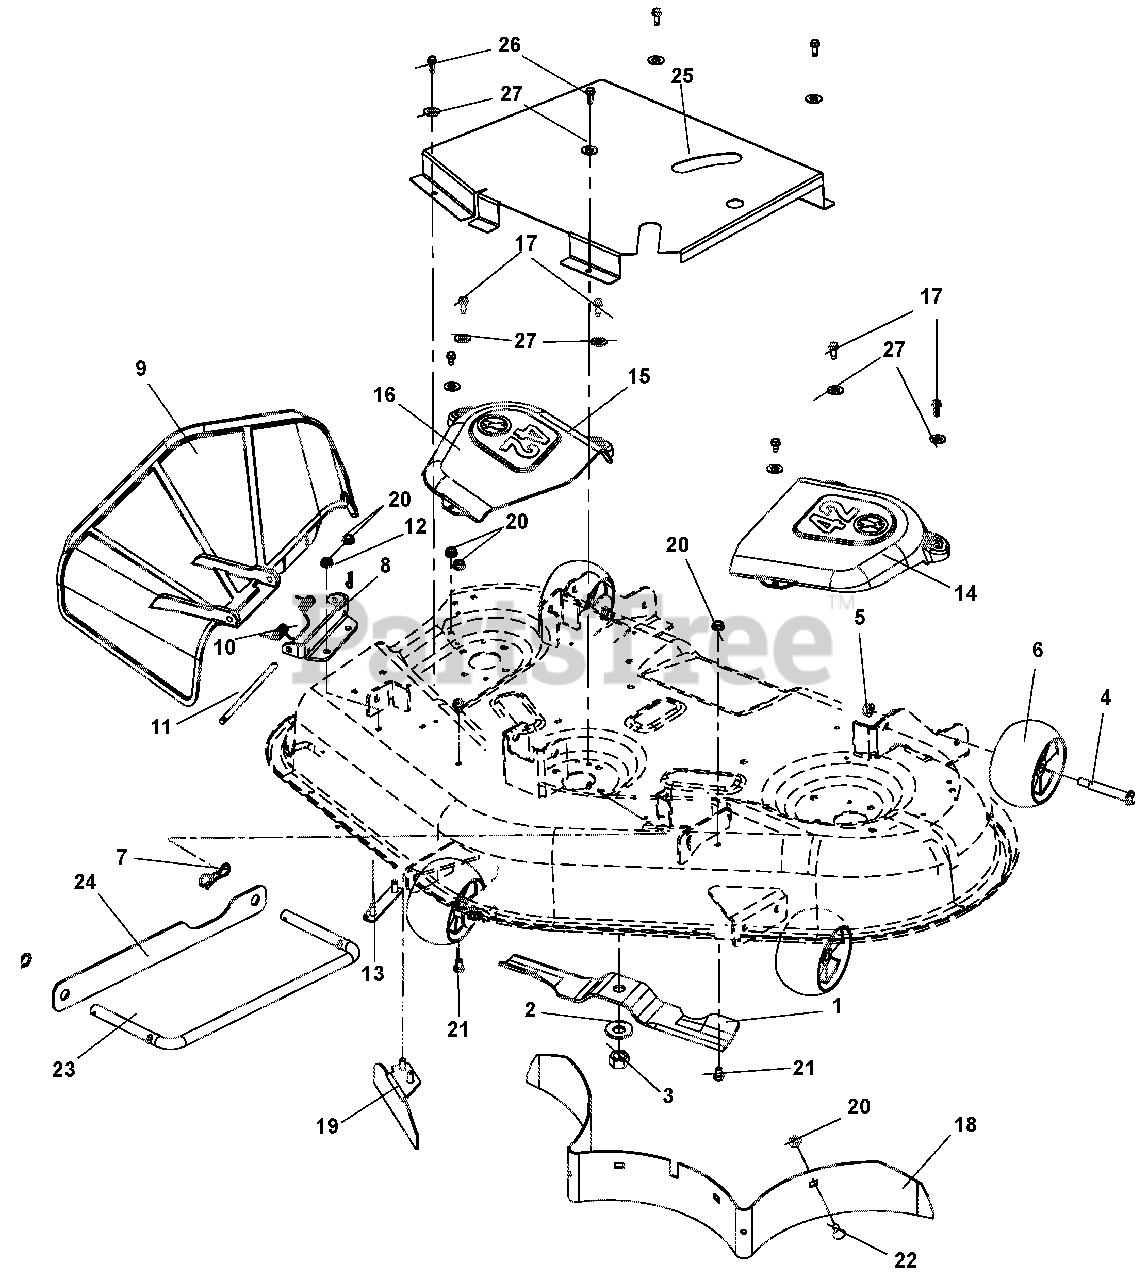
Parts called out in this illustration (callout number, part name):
1	Mower Blade, 14.83"
2	Washer, Bellville .63 x 1.625 x .14
3	Nut, Hex .62-18
4	Bolt, Shoulder .38-16 x 2.50 Hex Washer Head
5	Nut, Locking Top Flange .38-16
6	Anti-Scalp Wheel, 5 x 3 OS
7	Pin, Bow Tie Locking Cotter .091 x 1.875
8	Bracket, Discharge Chute Mount 42"
9	Discharge Chute – Molded
10	Spring, Torsion
11	Pin, 5/16 x 5.80"
12	Pin, Hair Internal .08 x .18 x 1.18
13	Weldment, Discharge Chute MT. Strap
14	Belt Cover, Left Hand 42"
15	Belt Cover, Right Hand 42"
16	Screw, Tapping .25-20 x .50 Hex Washer Head
17	Screw, Tapping .25-20 x .75 Hex Washer Head
18	Baffle, 42 Rear
19	Weldment – Baffle, Discharge 42"
20	Nut, Locking Top Flange .31-18
21	Bolt, Hex .31-18 x .50
22	Bolt, Round Head Square Neck .31-18 x .75
23	Wireform, Drag Link
24	Strap, Drag Link
25	CE Belt Guard
26	Screw, tap .25-20x.50
27	Nut, push .25x.50
